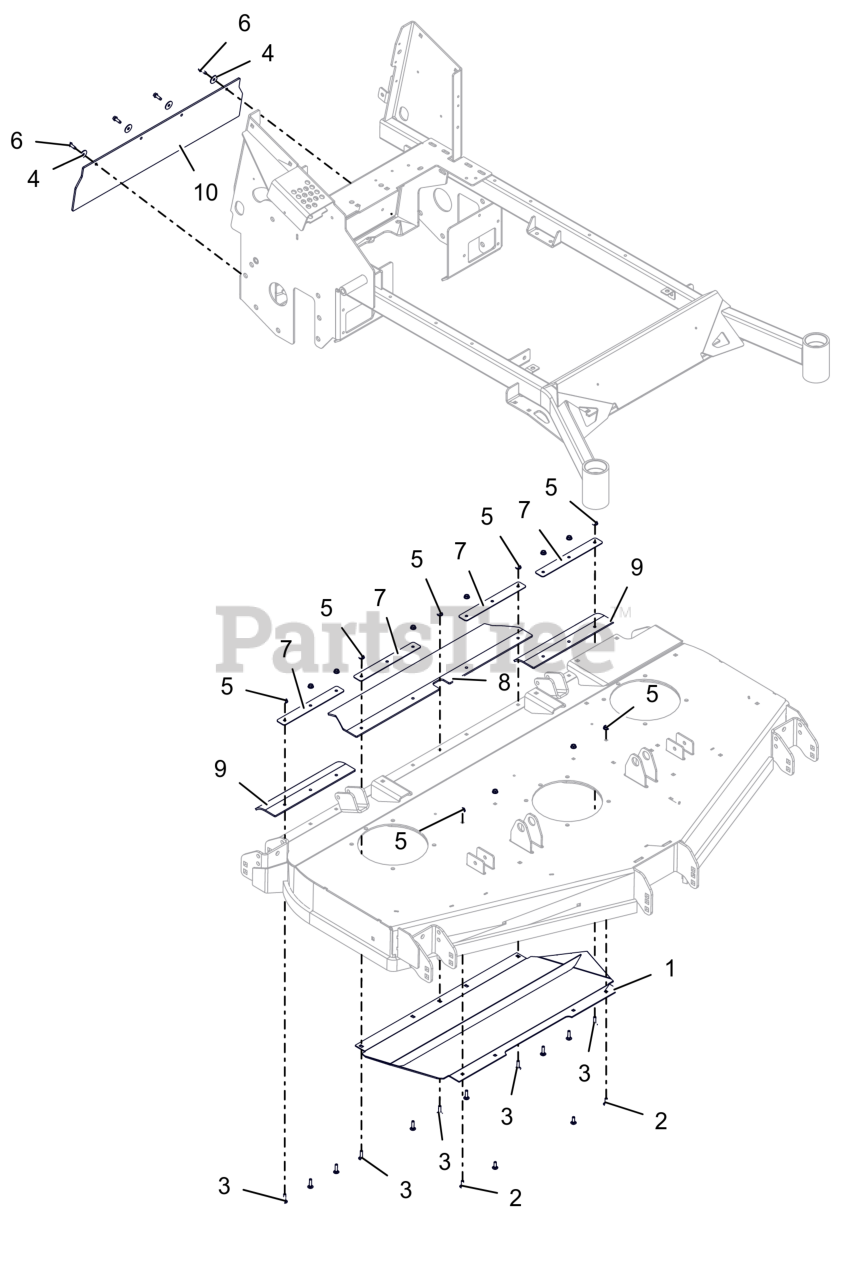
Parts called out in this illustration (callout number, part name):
1	WLDMT, DEFLECTOR BAFFLE (ORANGE)
2	BLT, RHSN .25-20X.750 G5 ZCC
3	BLT, RHSN .25-20X1.00 G5 ZCC
4	WSHR,FLT .281X1.000X.063 ZCC
5	NUT-LK-CTR-FLG .25-20 ZC120
6	SCR,TAP .25-20X.75 HWH TR ZCC
7	PLATE, CHUTE MTG (BLACK)
8	CHUTE, REAR DISCHARGE
9	FLAP, REAR DISCHARGE 60" TIRE
10	CHUTE, REAR DISCHARGE
